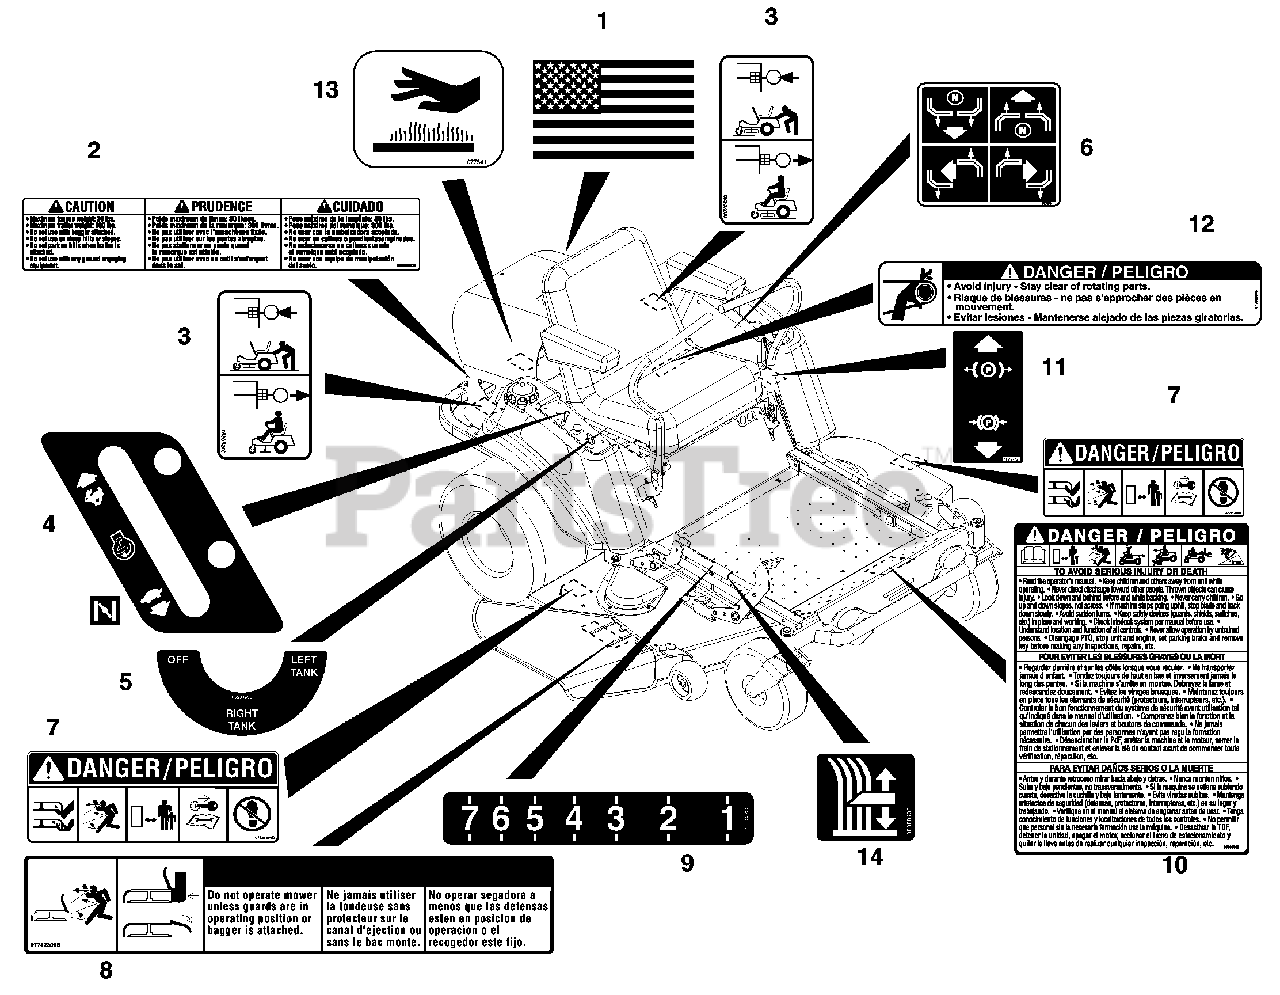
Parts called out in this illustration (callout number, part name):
1	Decal, American Flag
2	Decal, Trailer Hitch
3	Decal, Transmission Disconnect
4	Decal, Control
5	Decal, Fuel Value
6	Decal, Instructional Steering
7	Decal, Mower Pan Head Danger
8	Decal, Warning
9	Decal, Cut Height Zoom
10	Decal, Bilingual Danger
11	Decal, Parking Brake Lever
12	Decal, Danger
13	Decal, Hot Surface
14	Decal, Cut Height
